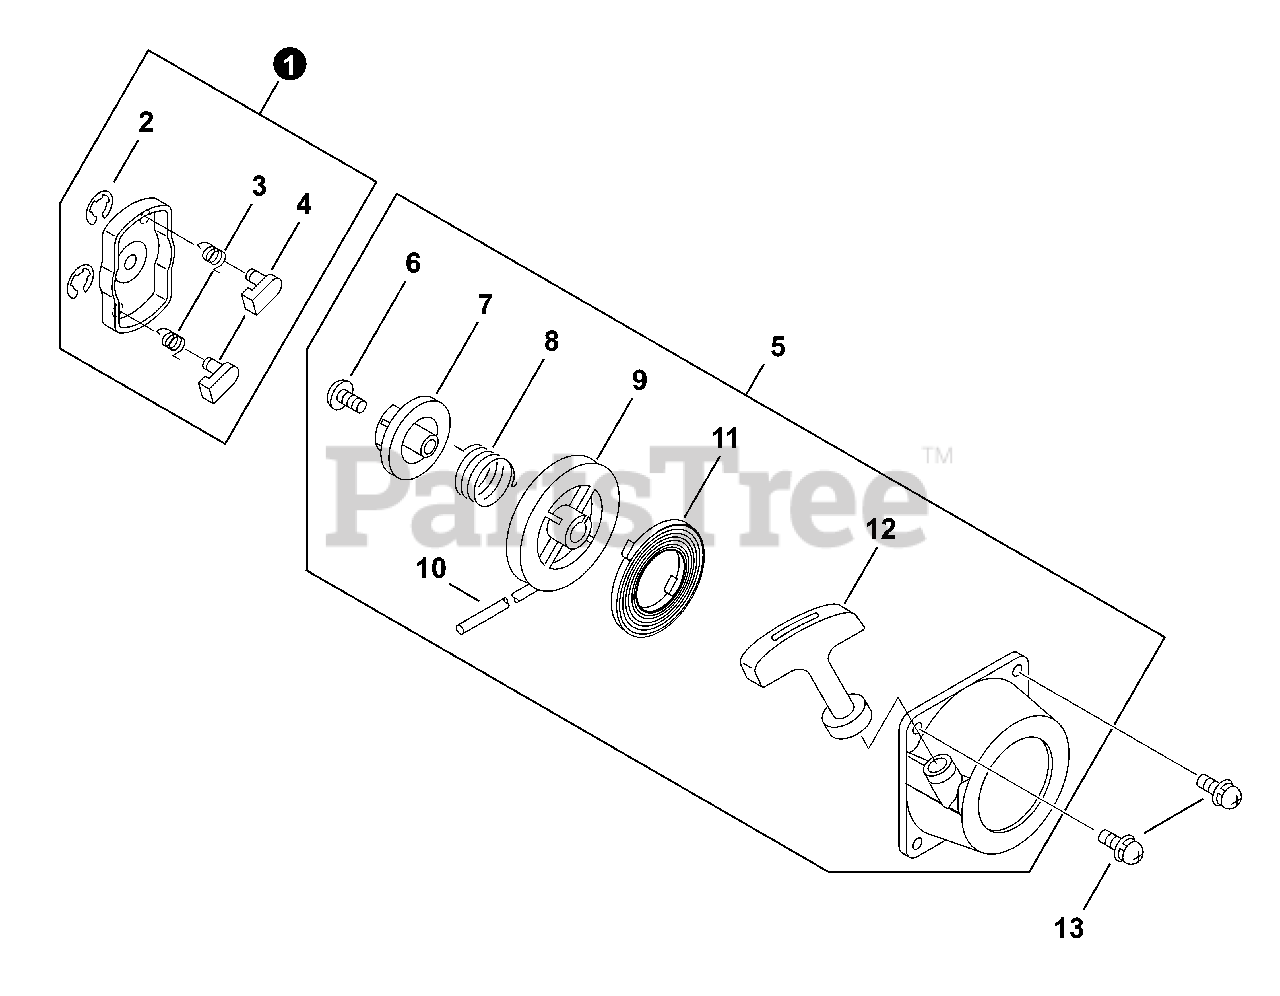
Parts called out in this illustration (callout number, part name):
1	PAWL ASSY, STARTER
2	E-RING 4
3	SPRING, RETURN
4	PAWL, STARTER
5	STARTER ASSY, RECOIL
6	SCREW
7	PLATE, CAM
8	SPRING, TORSION
9	REEL, ROPE
10	ROPE, STARTER
11	SPRING, RECOIL
12	GRIP, STARTER
13	SCREW 4×16
